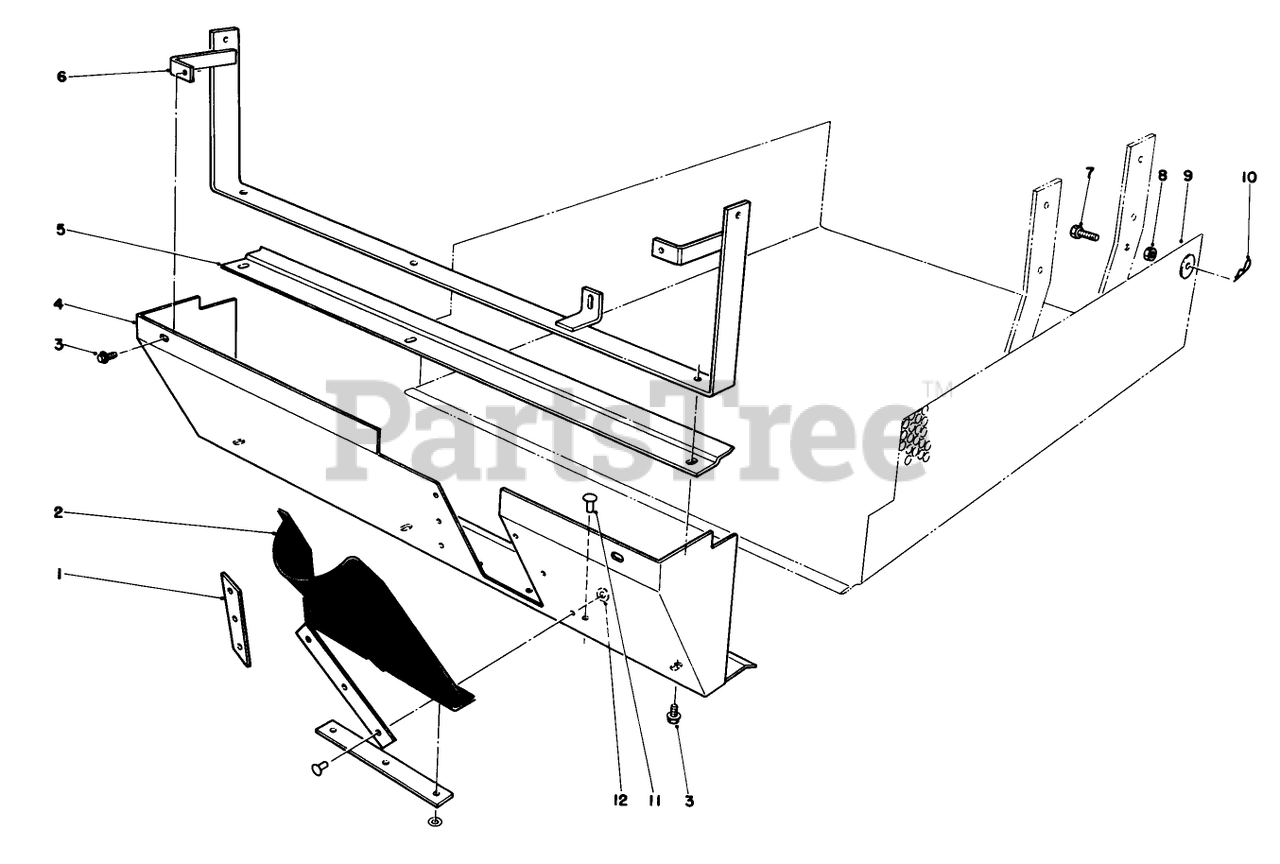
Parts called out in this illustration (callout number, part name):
1	RUBBER SUPPORT
2	RUBBER SHIELD
3	SCREW
4	Deflector
5	SCREEN SUPPORT B
6	DEFLECTOR MT WA R
7	Screw-Special
8	NUT-LOCK, NI
9	GRASS SCREEN WA
10	PIN-COTTER, HAIR
11	RIVET-POP
12	WASHER-FLAT
